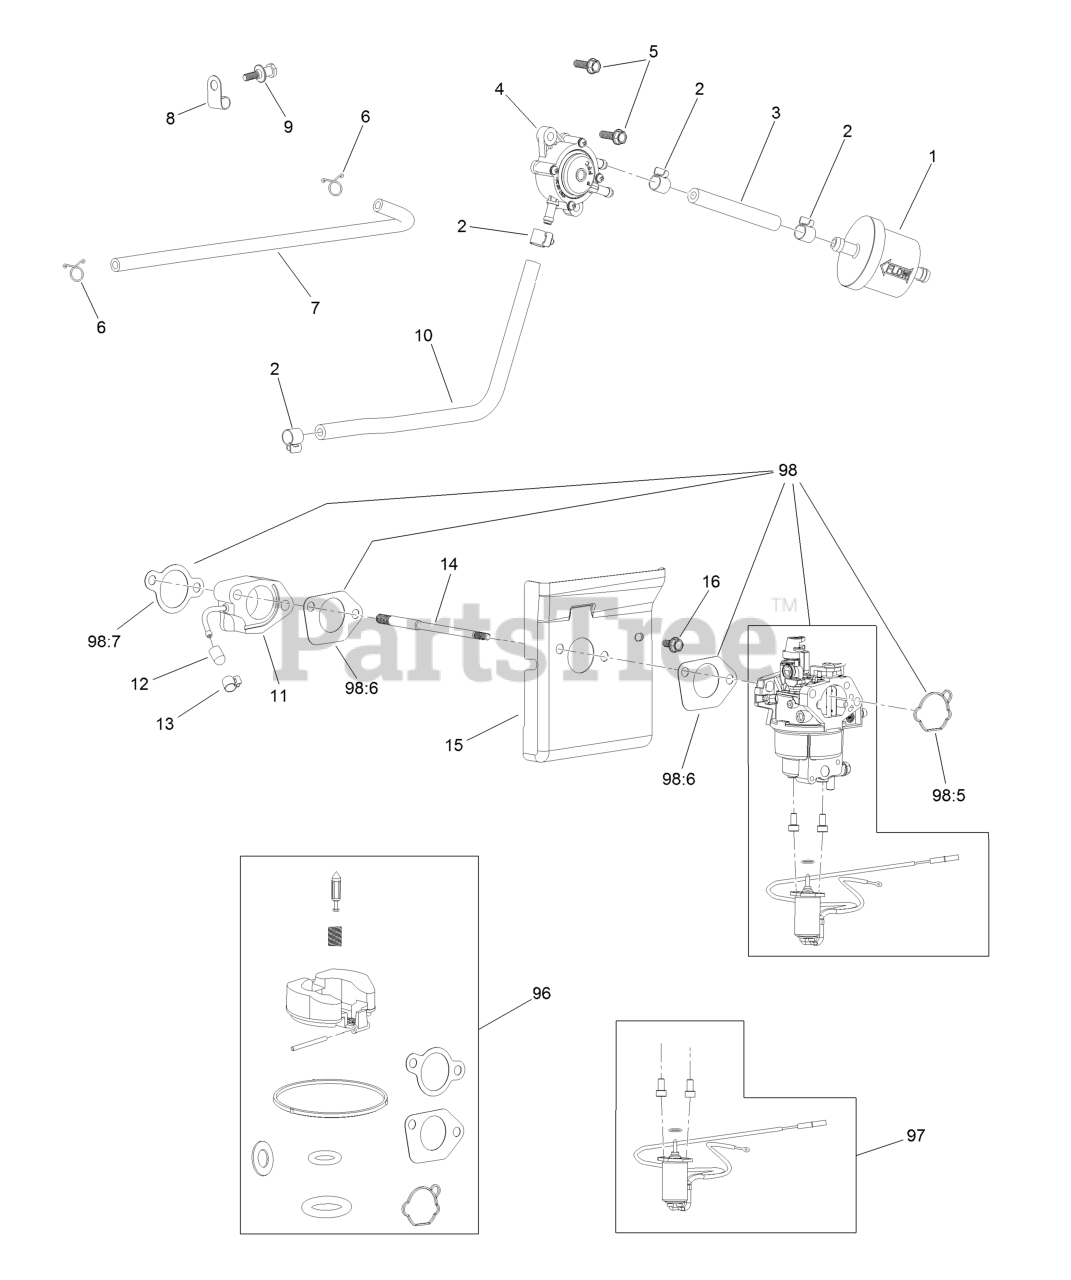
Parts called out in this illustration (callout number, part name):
1	FILTER-FUEL
2	CLAMP-FUEL LINE
3	LINE-FUEL
4	PUMP-PULSE, FUEL
5	SCREW-HHF
6	CLAMP-HOSE
7	LINE-PULSE
8	CLAMP-J
9	SCREW-SHOULDER, HH
10	LINE-FUEL
11	INSULATOR-CARBURETOR
12	CAP-SEAL
13	CLAMP-HOSE
14	STUD-MOUNT, CARBURETOR
16	SCREW-HHF
96	CARB REPAIR KIT WITH GASK
97	SOLENOID KIT
98:5	GASKET-CARBURETOR
98:6	GASKET-CARBURETOR
98:7	GASKET-CARBURETOR
